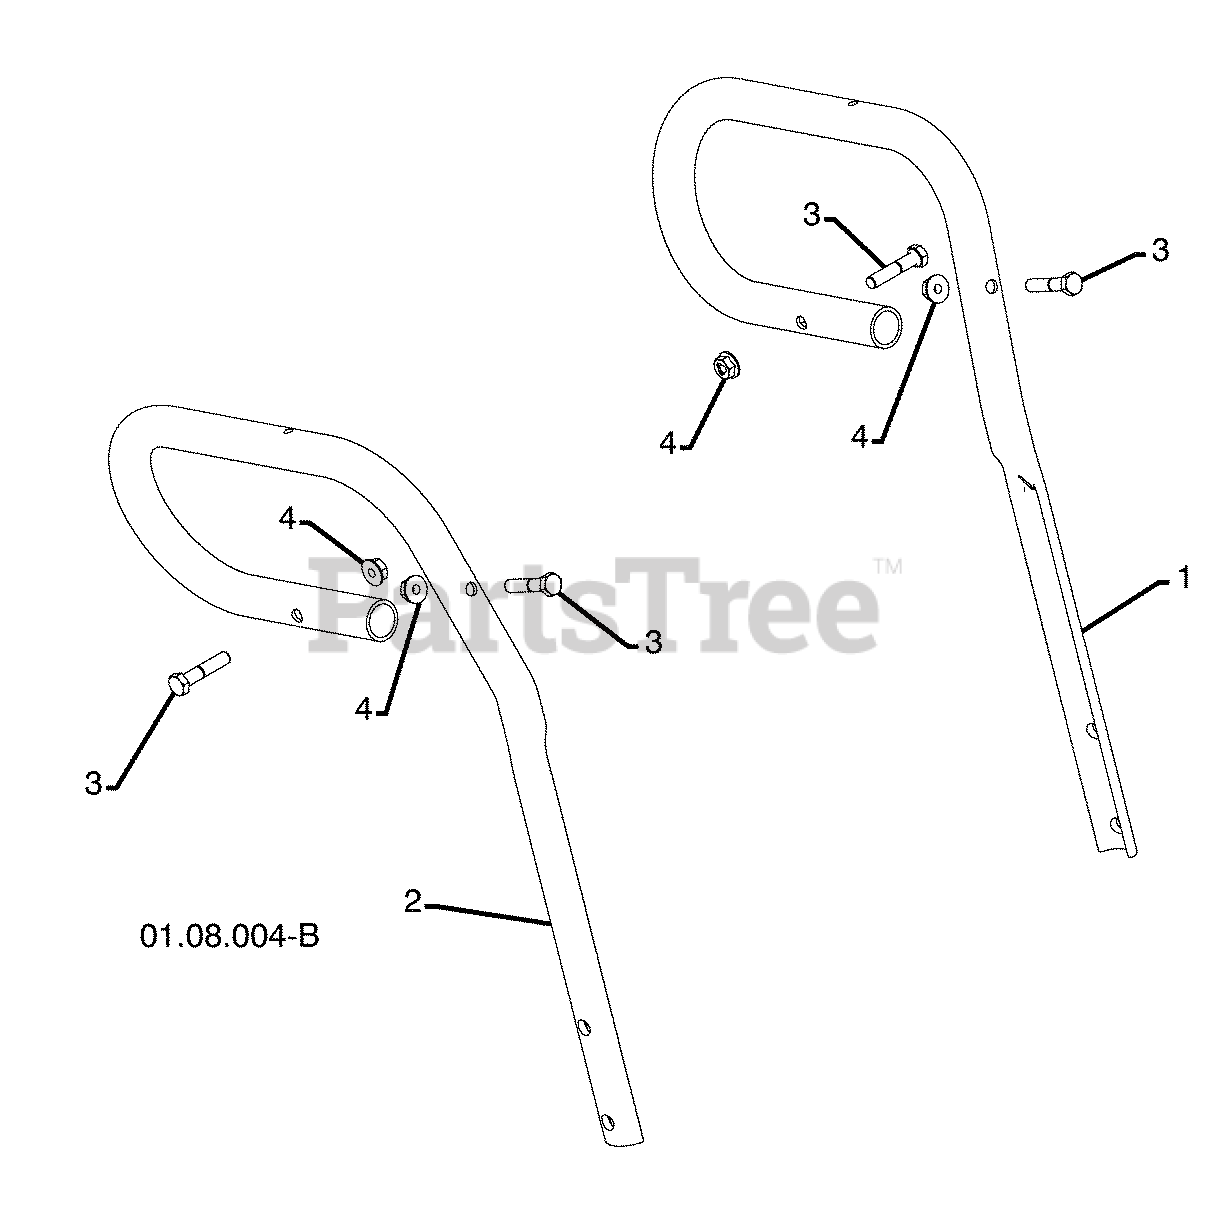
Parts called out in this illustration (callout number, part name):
1	LOOP HANDLE LH
2	LOOP HANDLE RH
3	SCREW 5/16-18 X 1.50
4	NUT 5/16-18
